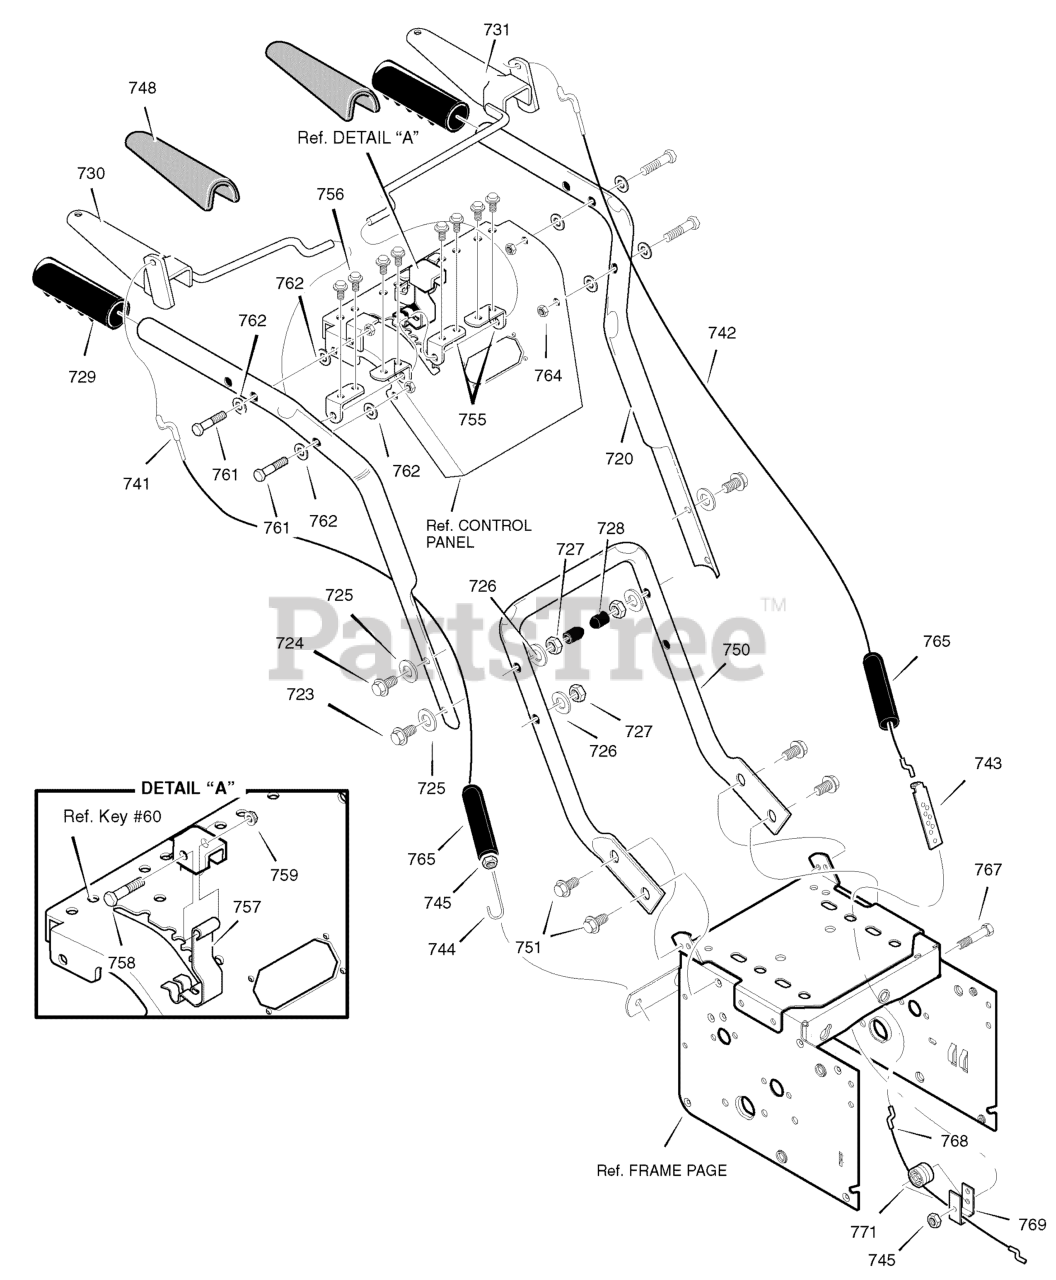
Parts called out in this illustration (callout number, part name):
720	HANDLE, UPPER LH
721	HANDLE, UPPER RH
723	SCREW
724	SCREW
725	WASHER, FLAT
726	WASHER
727	NUT, REGHEX
728	STOP, PLASTIC
729	GRIP-HANDLE
730	LEVER, ASSY CLUTCH DRIVE RH
731	LEVER, ASSY CLUTCH DRIVE LH
741	CABLE, AUGER CLUTCH
742	CABLE, AUGER DRIVE
743	BRACKET, CABLE ADJUSTER
744	SPRING, AUGER CLUTCH
745	NUT, 1/4-20
748	GRIP, CLUTCH HANDLE
750	HANDLE, LOWER
751	SCREW
754	SCREW
755	BRKT, ROD
757	SPRING, CAM LOCK
758	BOLT, HEX
759	NUT
762	WASHER, FLAT
764	NUT, HEX
765	BOOT, CLUTCH SPRING
767	BOLT, HEX 1/4-20 X 1.50
768	CABLE, LOWER DRIVE 12"
769	BRACKET, CABLE SPOOL YZ
771	SPOOL-CABLE, AUGRT CLUTCH
